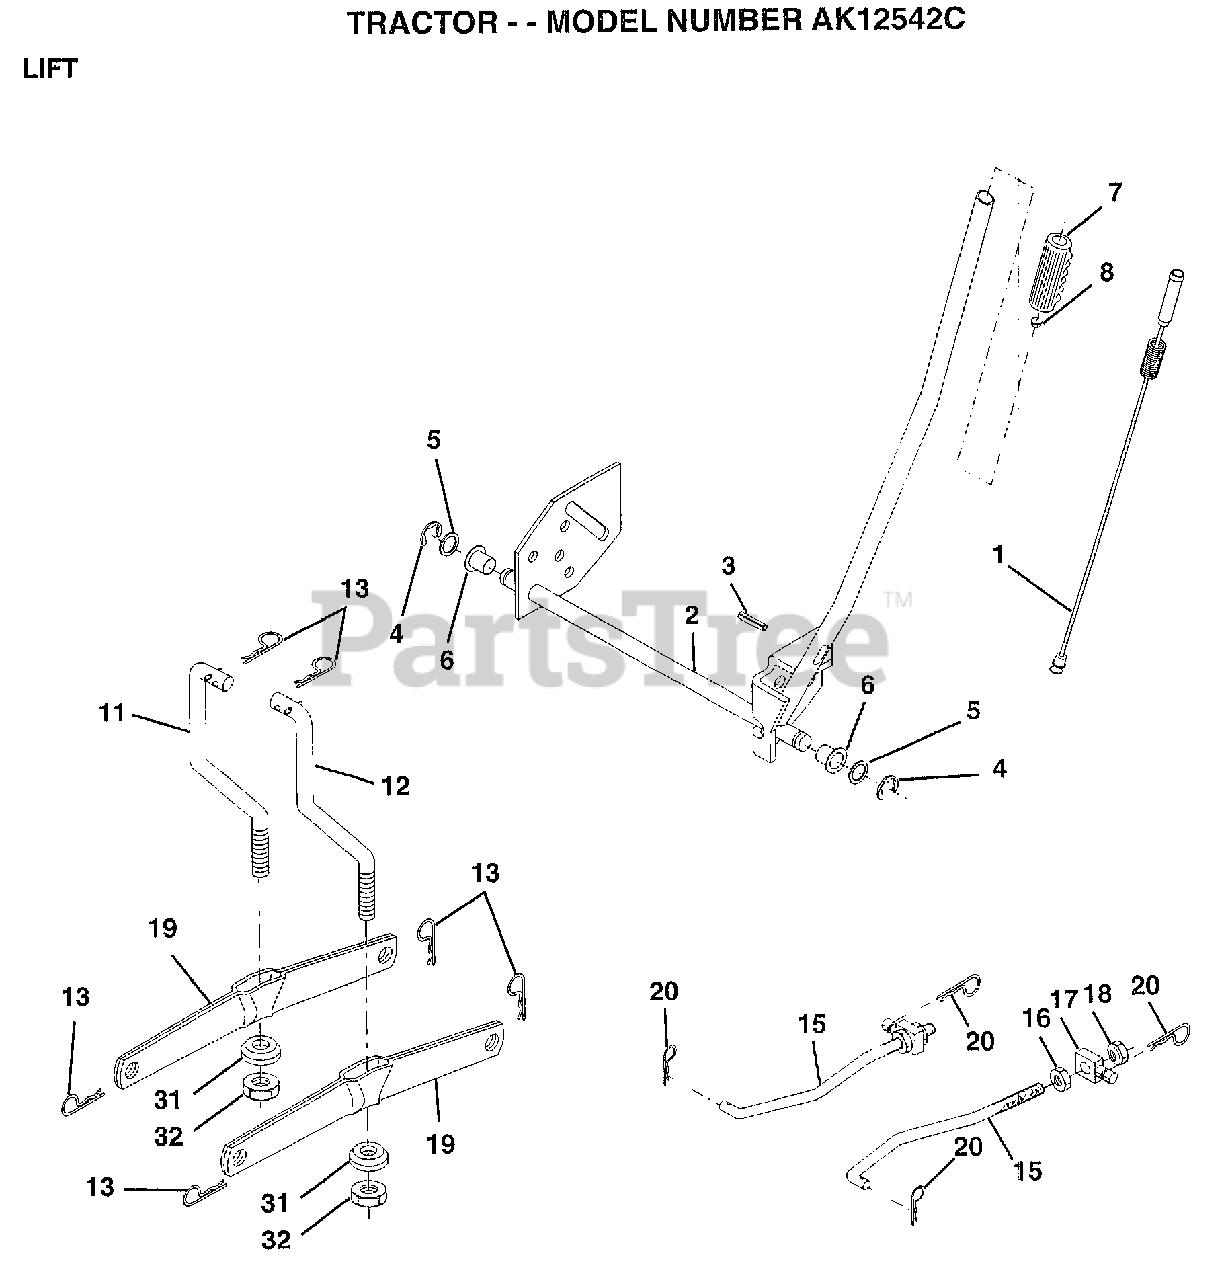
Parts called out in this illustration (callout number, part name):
1	WIRE ASM W.SPRING
2	"SHAFT ASM LIFT,RH"
3	PIN-GROOVE LT
5	WASHER
6	NYLON BEARING
7	GRIP
15	LINK.FRONT
16	NUT
17	TRUNION
18	NUT LTV
19	ARM SUSP REAR
20	RETAINER SPRING
31	BEARING PVT LH
32	NUT.CROWNLOCK.3/8
